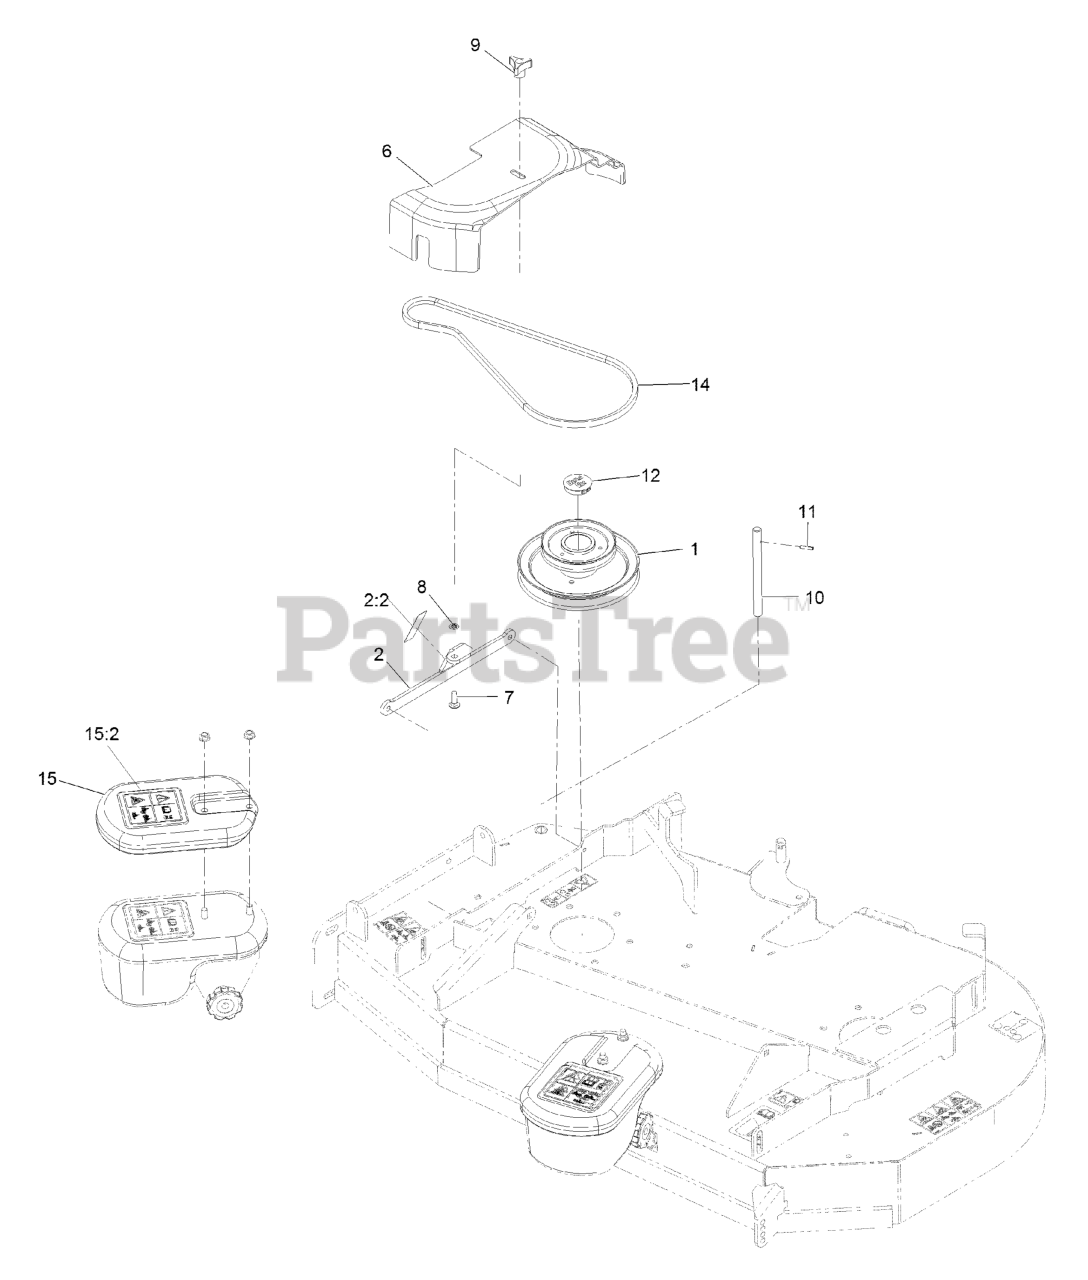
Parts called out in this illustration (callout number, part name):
1	Jackshaft- Uv Drive
2	ASM-Cvr Brkt W/Decal
2:2	DECAL-DANGER
6	Cover-Belt
7	BOLT-CARR
8	RING-RETAINING, BOLT
9	KNOB-3 PRONG
10	SHAFT-CATCHER, GRASS
11	PIN-ROLL
12	PLUG, BLACK NYLON 1.75
15:2	DECAL-WARNING, TRACTION
